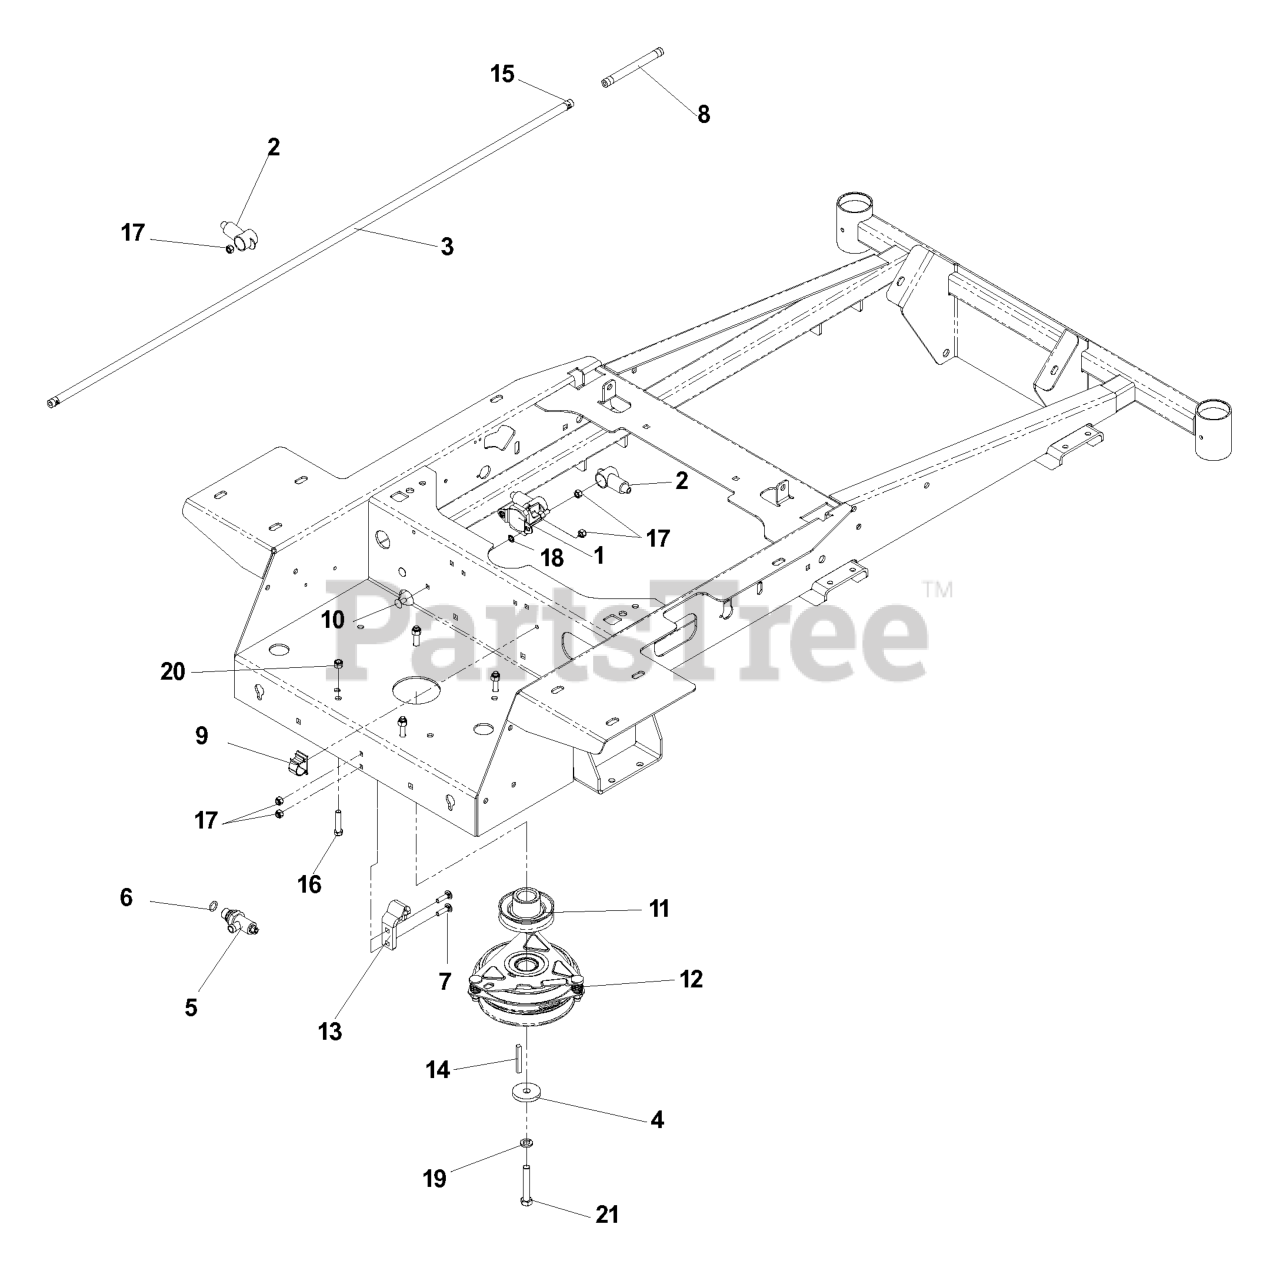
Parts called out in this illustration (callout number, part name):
4	SPINDLE WASHER
5	VALVE ASSEMBLY
7	RHSNB, 1/4-20 X 1, GR5
8	FUEL LINE 5"
9	PUSH-MOUNT WIRE CLIP
10	RHSSNB, 1/4-20X5/8
11	PULLEY, DRIVE
12	CLUTCH, 150 FT/LBS
13	TIE DOWN, CLUTCH
14	KEY 1/4 SQ X 2
15	HOSE CLAMP
16	CAPSCREW 5/16 X 1/1/2 HEX HEAD
17	NUT.1/4-20.HEX.NYLOC.ZD
18	WASHER 1/4 INT TOOTH
19	WASHER 7/16 LOCK
20	NUT 5/16 NYLOC
21	BOLT 7/16F X 2 1/2
